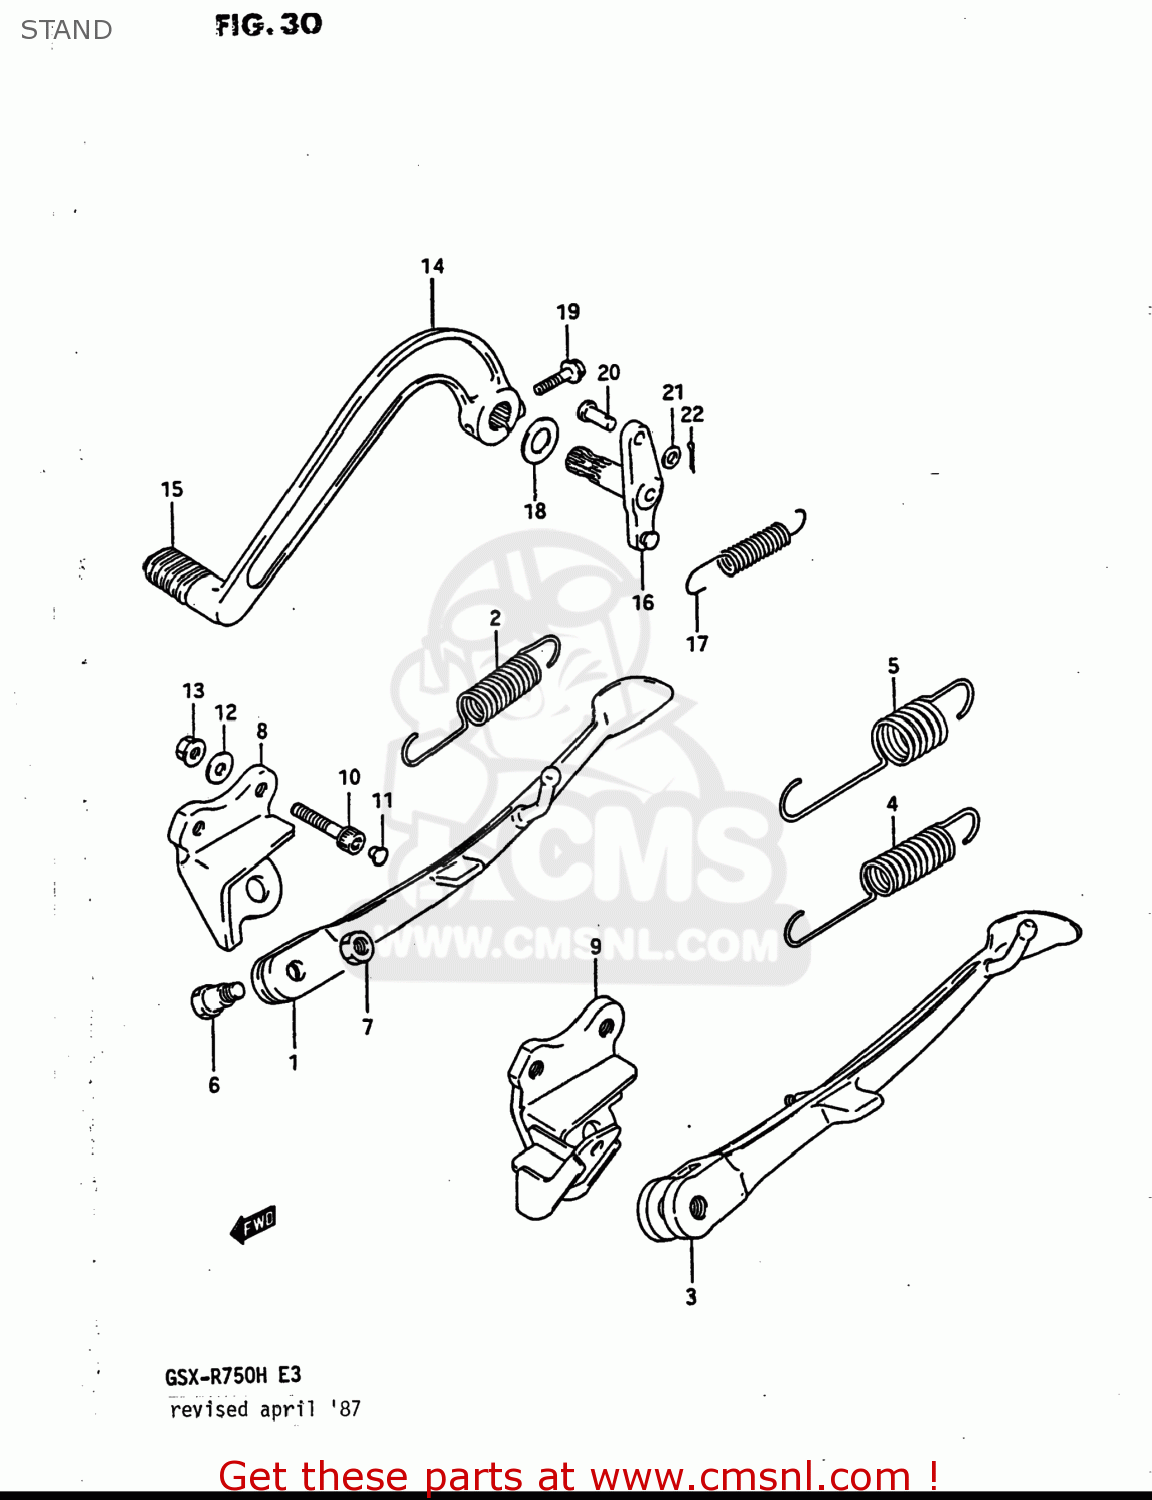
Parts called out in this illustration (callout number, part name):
1	STAND,SIDE
2	SPRING
3	STAND,PROP
4	SPRING
5	SPRING
6	BOLT(10X38)
7	NUT
8	BRACKET,SIDE STAND
9	BRACKET,SIDE STAND
10	BOLT, FRONT RH
11	CAP,ENGINE MOUNTING
12	WASHER
13	NUT
14	PEDAL,BRAKE
15	RUBBER,BRAKE PEDAL
16	ARM COMP,BRAKE ROD
17	SPRING
18	WASHER,BRAKE PEDAL
19	BOLT
20	PIN
21	WASHER
22	PIN
23	STAND,CENTER
24	GRIP,L
